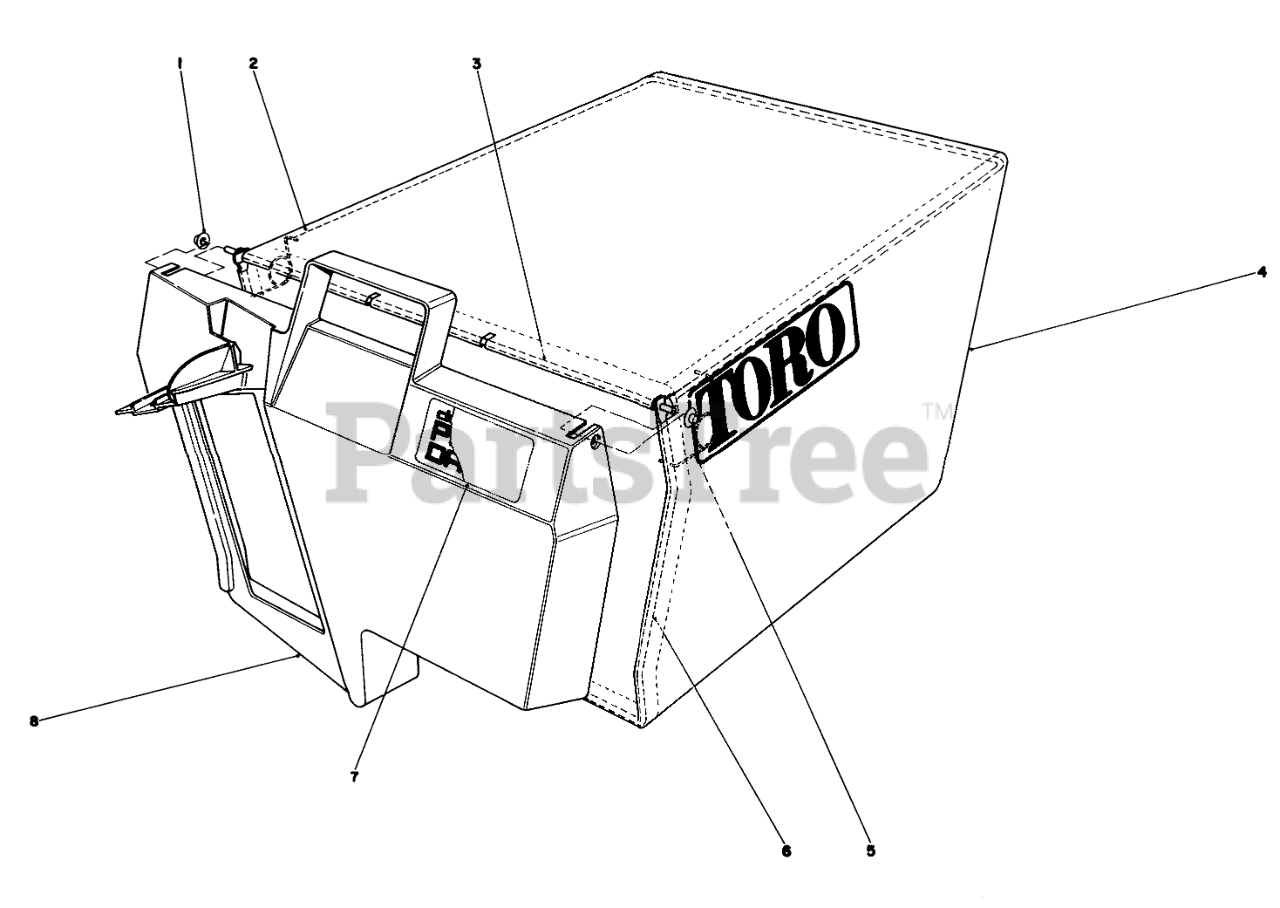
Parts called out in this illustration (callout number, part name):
1	NUT-PUSH
2	FRAME-BAG, UPPER
3	HINGE-DOOR, BAG
4	Bag
5	SPRING
6	FRAME-BAG
7	BAG DOOR DECAL
8	Door Grass Bag
